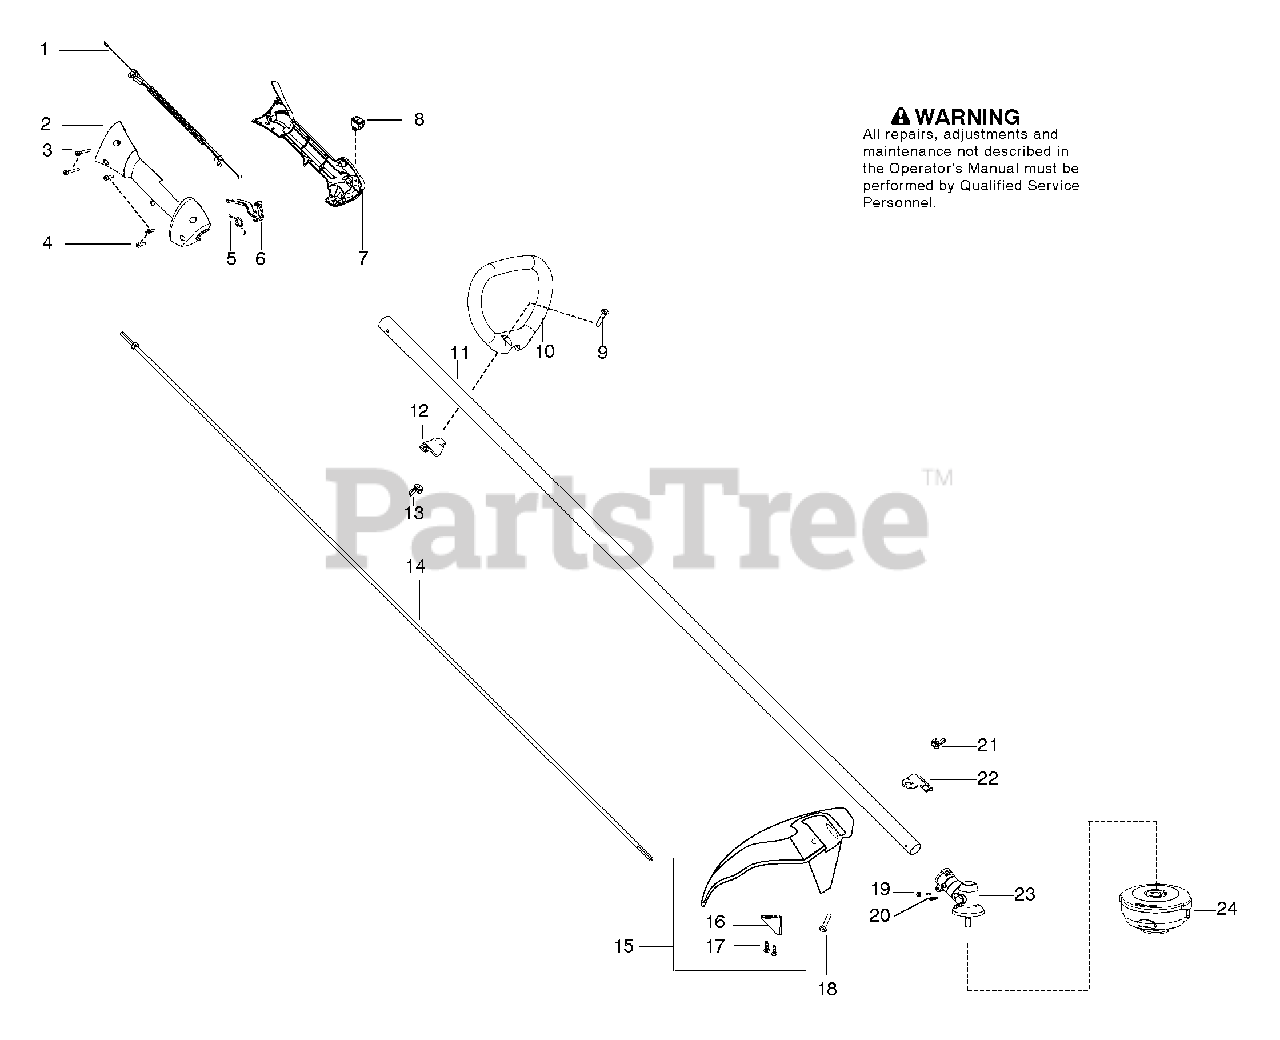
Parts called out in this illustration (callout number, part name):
1	Assy-Cable/Wire Harness
2	Housing-Throttle (RH)
5	Spring-Trigger
7	Housing-Throttle (LH)
8	Switch
10	Handle-Assist
11	Kit-Driveshaft
12	Clamp-Handle
13	Wingnut
14	Flexshaft 57"
15	Kit-Shield
16	Limiter-Line
21	Wingnut
22	Bracket-Shield
23	Gearbox 1"
24	Assy-T25 Cutting Head
